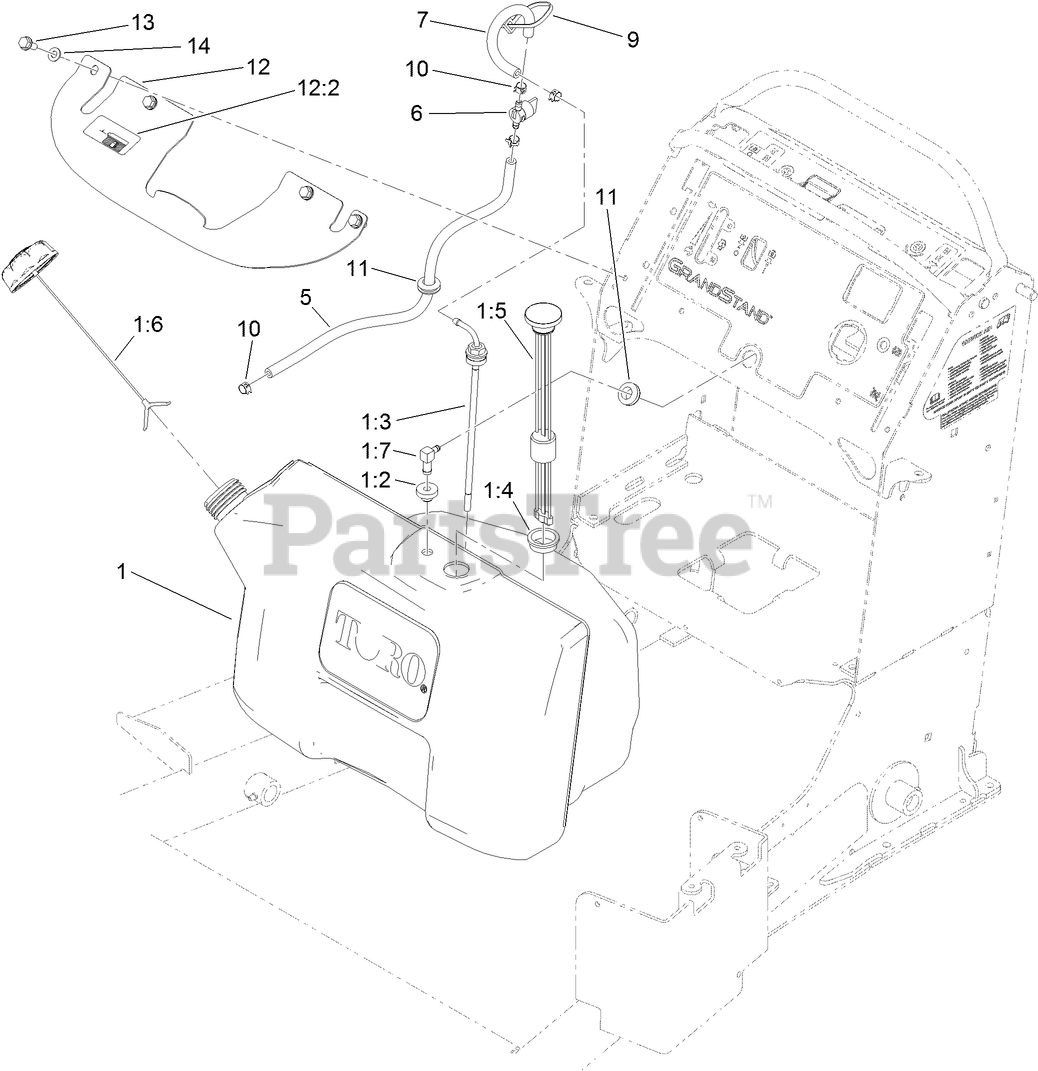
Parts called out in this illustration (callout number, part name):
1	TANK ASM
1:2	BUSHING
1:3	ELBOW-90 DEG
1:4	GROMMET
1:5	GUAGE-FUEL
1:6	CAP-FUEL, RATCHETING
1:7	FITTING-FUEL, BULKHEAD
5	HOSE-FUEL
6	VALVE-FUEL
7	HOSE-FUEL
9	TIE-CABLE
10	CLAMP-HOSE
11	GROMMET
12	BRACKET-TANK
12:2	DECAL-FILL, FUEL
13	SCREW-HWHTF
14	WASHER-FLAT
